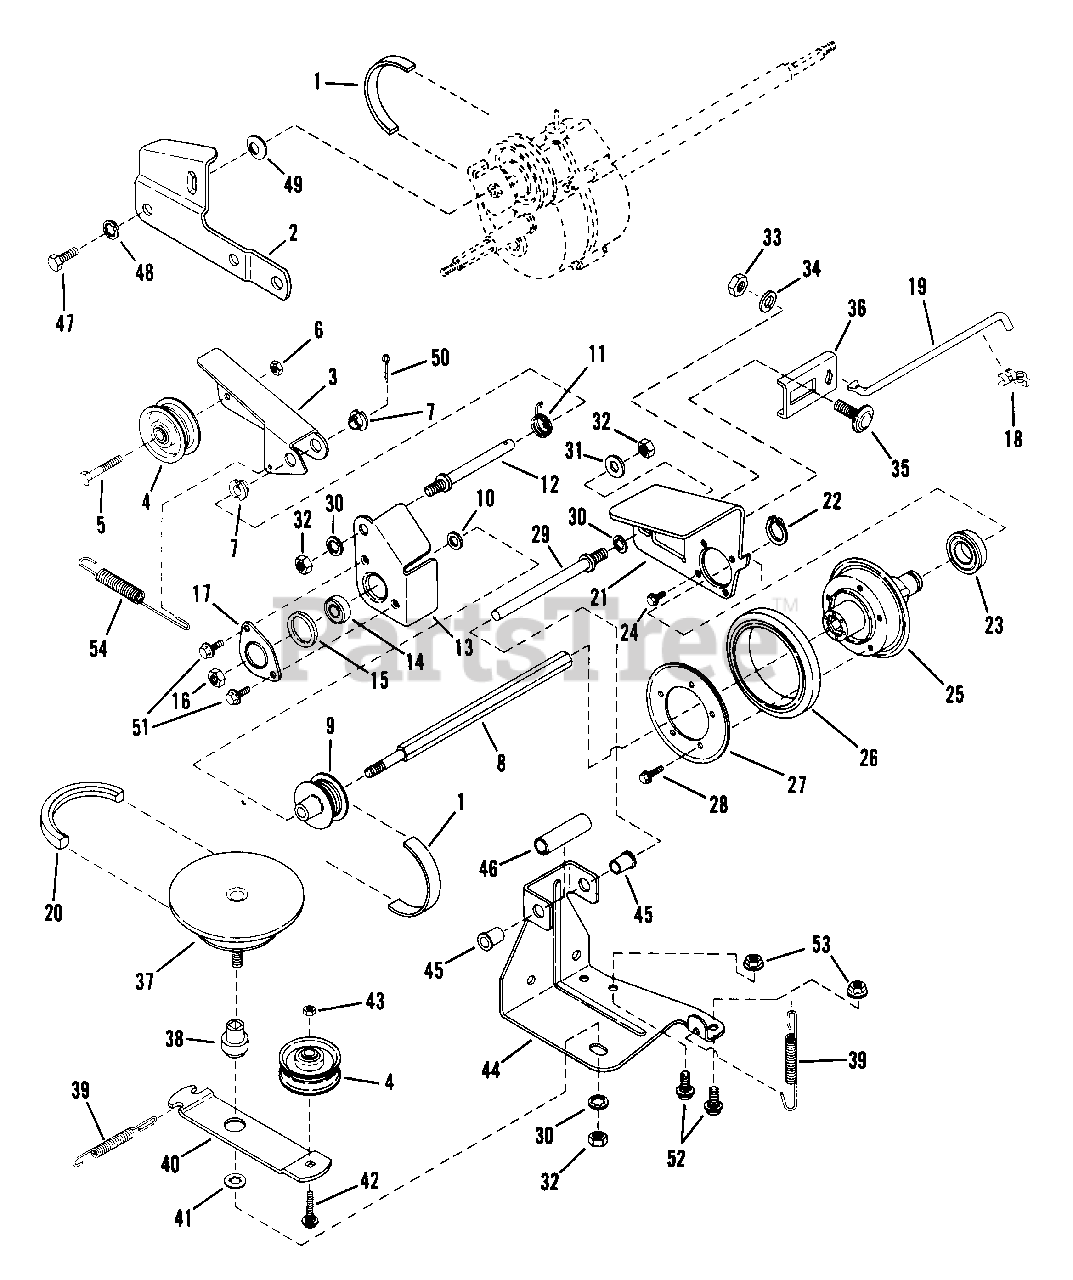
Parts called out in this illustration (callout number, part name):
1	BELT, Poly-Vee
2	LINK, Differential
3	ARM, Clutch Idler
4	PULLEY, Idler
5	SCREW, 1/4-28 x 1-3/8" Hex Head Cap
6	NUT, 1/4-28 Hex Lock
7	BUSHING, 3/8 I.D. Nylon
8	SHAFT, Hex
9	PULLEY
10	WASHER
11	SPRING, Torsion
12	STUD
13	HOLDER, Bearing (Inner Half)
14	BEARING, Ball
15	O-RING
16	NUT, 3/8 Hex Center Lock
17	HOLDER, Bearing (Outer Half)
18	CLIP, 1/4 Right Arc (Transfer Rod)
19	ROD, Transfer
20	BELT, Engine Drive
21	PLATE, Thrust
22	RING, Retaining
23	BEARING, Ball
24	SCREW, #10-32 x 1/4" Self-Tapping Machine
25	ASSEMBLY, Hub
26	RING, Driven
27	PLATE, Ring Retaining
28	SCREW, #10-24 x 1/2" Hex Washer Self-Tap (Torx)
29	GUIDE, Thrust Plate
30	WASHER, 3/8 Internal Tooth Lock
31	WASHER, 3/8" Flat
32	NUT, 3/8-24 Hex
33	NUT, 5/16-18 Hex
34	WASHER, 5/16 Split Lock
35	BOLT, 5/16-18 x 3/4" Carriage
36	CONNECTOR, Transfer Rod
37	ASSEMBLY, Drive Disc
38	BUSHING
39	SPRING (Wheel Drive & Idler)
40	ARM, Idler
41	RETAINER, 3/8 Bolt
42	BOLT, 1/4-20 x 1-1/4" Carriage
43	NUT, 1/4-20 Hex Center Lock
44	BRACKET, Deck
45	BUSHING, Flange
46	SPACER
47	SCREW, 5/16-18 x 1/2" Hex Head Cap
48	WASHER, 5/16 Internal Tooth Lock
49	WASHER, Spring
50	PIN, 3/32 x 1/2" Cotter
51	SCREW, 1/4-20 x 1/2" Self-Tapping
52	BOLT, 5/16-18 x 5/8" Short Neck Carriage
53	NUT, 5/16-18 Hex Flange Lock
54	SPRING, Clutch
